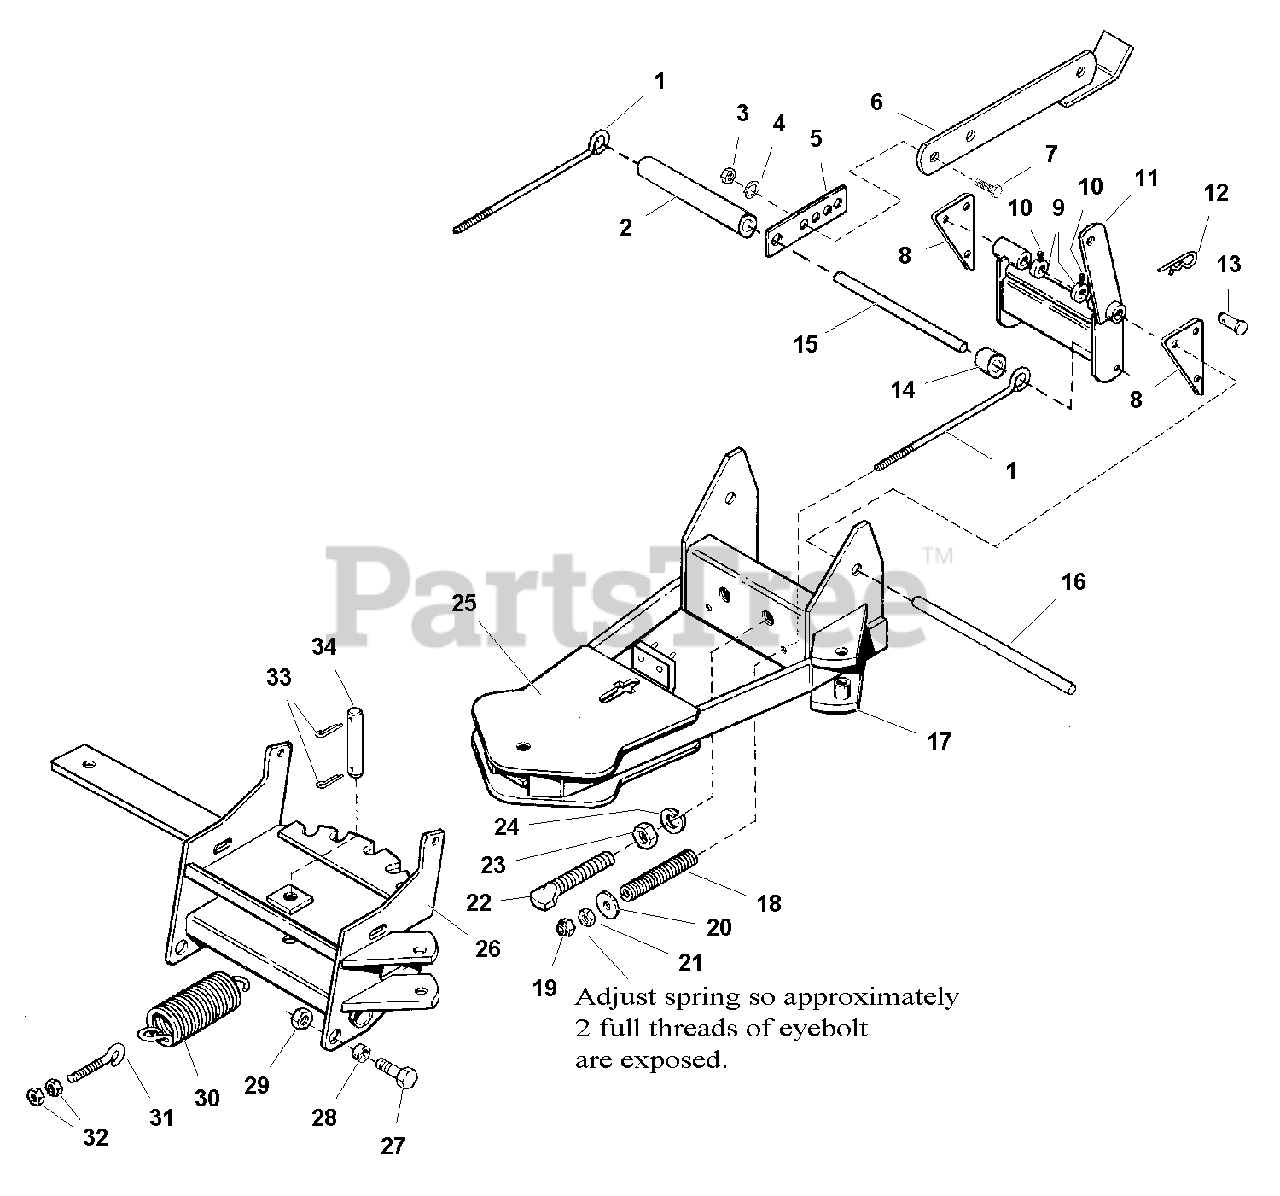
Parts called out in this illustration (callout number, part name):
1	EYEBOLT, 3/8-16
3	NUT, Hex, 1/2-13
4	WASHER, Lock, 1/2
5	BAR, Lift, Front
6	LIFT BAR ASSEMBLY
7	CAPSCREW, Hex Head, 1/2-13 x 1-3/4
8	ANCHOR, Front
9	SET COLLAR
10	SETSCREW, Square Head, Cup Point, 5/16-18 x 1/2, GR8
11	PIVOT ASSEMBLY, Hitch
12	CLIP, Hairpin
13	PIN, Clevis, 5/8 x 2-1/4
16	SHAFT, Inner
17	HITCH ASSEMBLY
18	SPRING, Compression
19	NUT, Hex Jam, 3/8-16
20	WASHER, 3/8
21	NUT, Hex, 3/8-16
22	STUD, 3/4-10
23	NUT, Hex, 3/4-10
24	WASHER, Lock, 3/4
25	HITCH ASSEMBLY
26	FRAME ASSEMBLY
27	CAPSCREW, Hex Head, 1/2-13 x 1-1/2
29	NUT, Lock, 1/2-13
30	SPRING, Extension
31	EYEBOLT, 5/16-18
32	NUT, Hex, 5/16-18
33	PIN, Cotter 3/16 x 1-1/4
